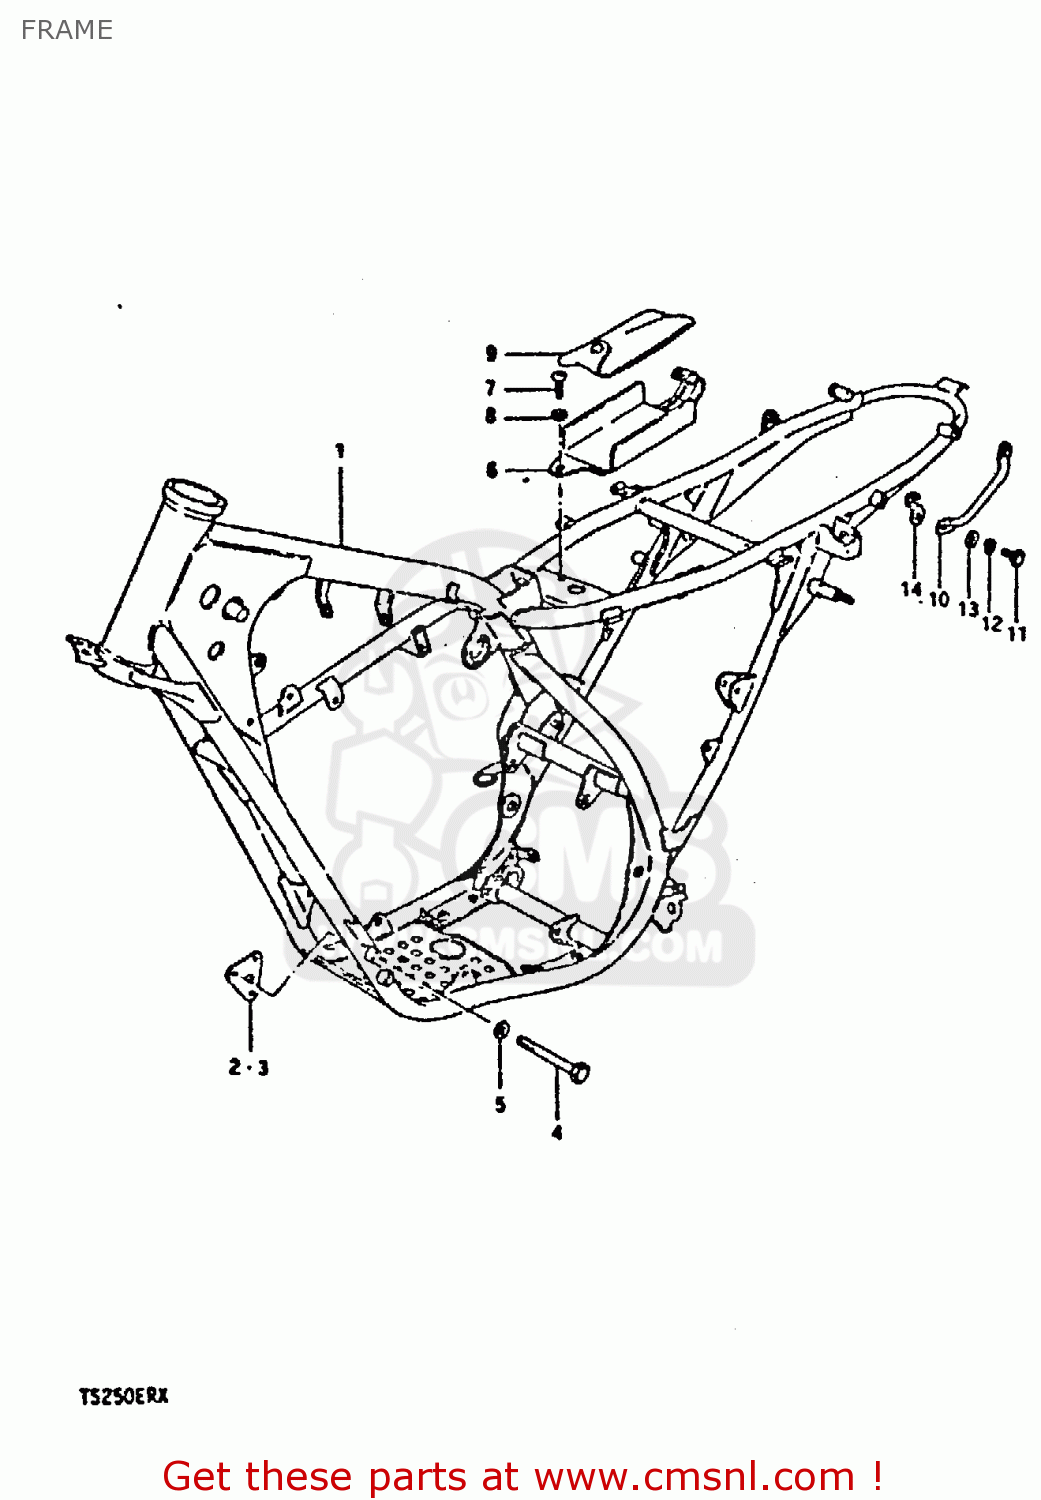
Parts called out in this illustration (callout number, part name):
1	FRAME
2	PLATE,ENGINE MOUNTING
3	PLATE,ENG MTG,L
4	BOLT 8X55
5	WASHER
6	HOLDER,TOOL
7	SCREW
8	WASHER
9	TOOL SET
10	GRIP,FRAME HANDLE
11	BOLT
12	LOCK WASHER
13	WASHER
14	HOOK,HELMET HOLDER
